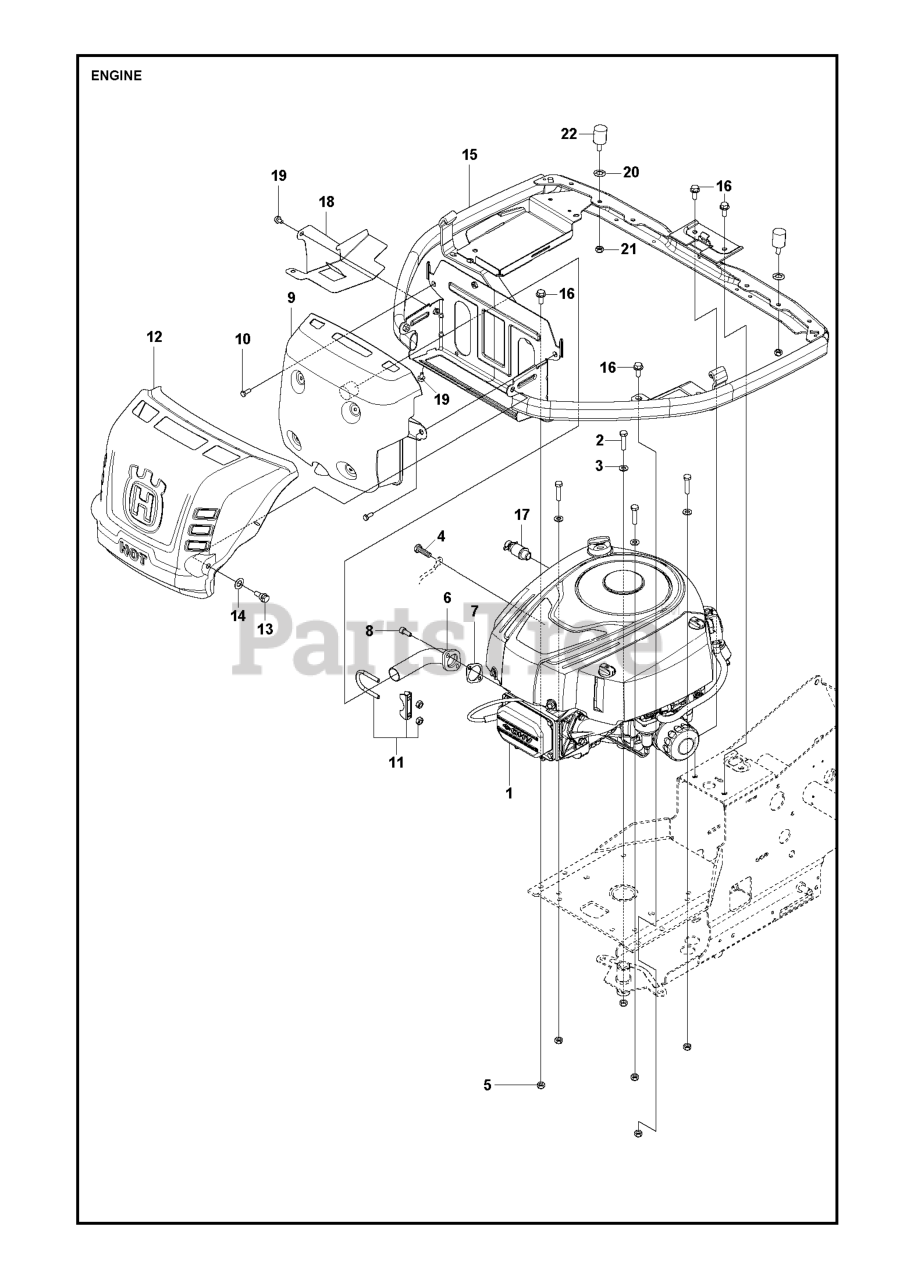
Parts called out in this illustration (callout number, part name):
3	WASHER BRB 8.4X17
5	LOCKNUT M8
11	CLAMP ASSY EXHAUST
12	HEAT SHIELD
14	SPRINGWASHER
17	VALUE.OIL.DRAIN
19	SCREW EHHFM
20	SPRINGWASHER
21	LOCKNUT M8
